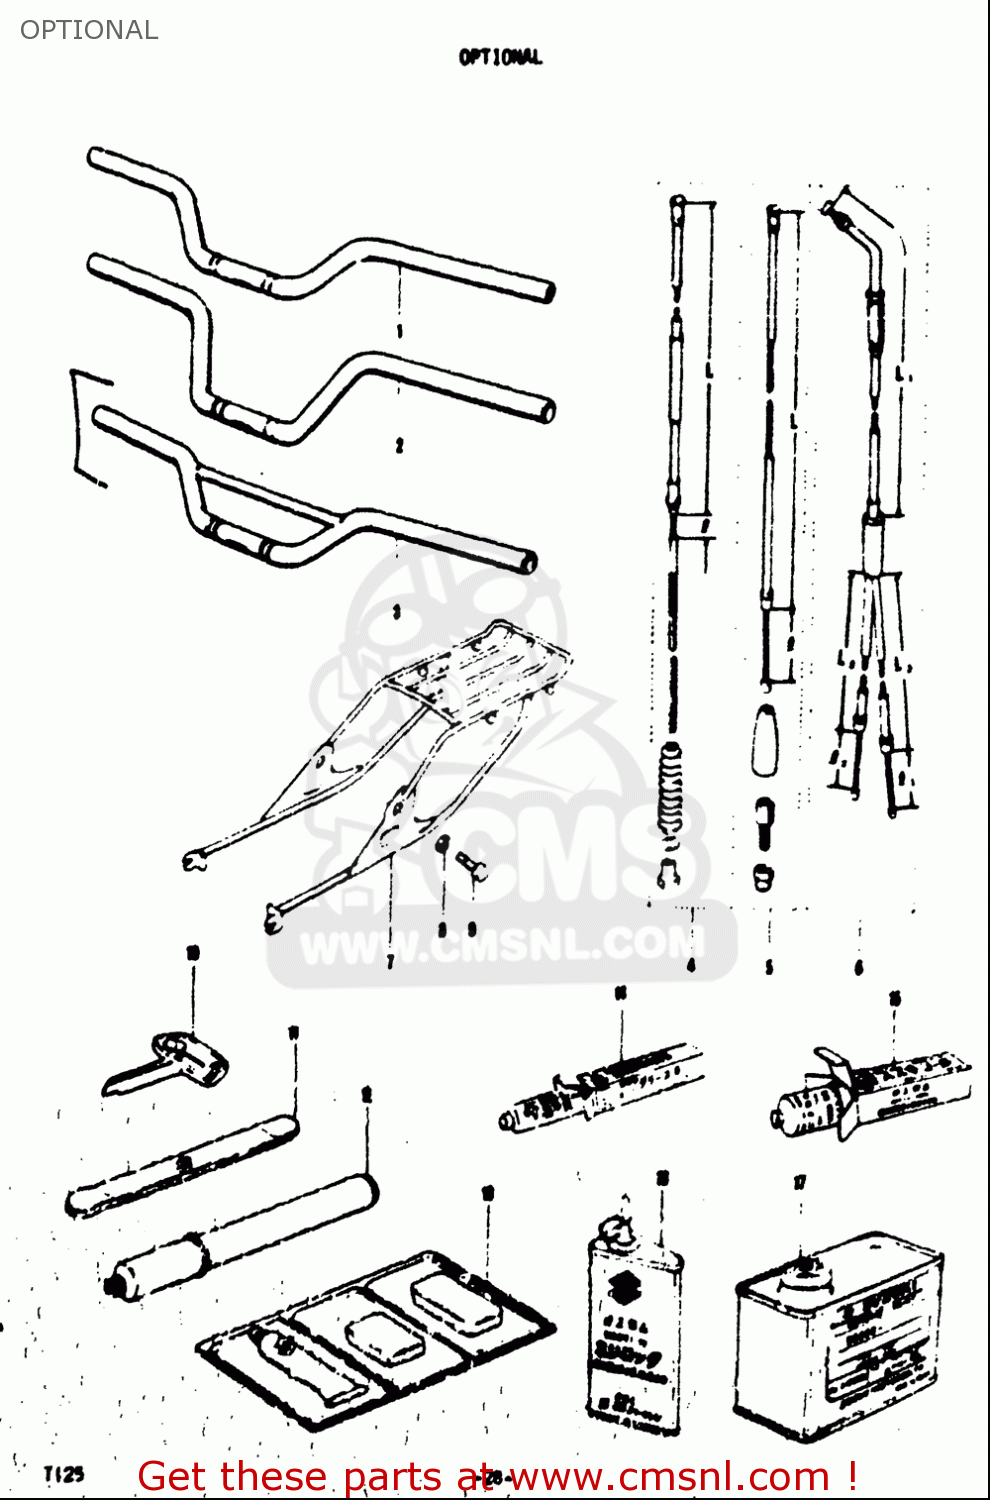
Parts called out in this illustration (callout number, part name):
3	HANDLEBAR
5	WIRE,CLUTCH
8	WASHER,LOCK
9	BOLT
11	LEVER,TIRE
